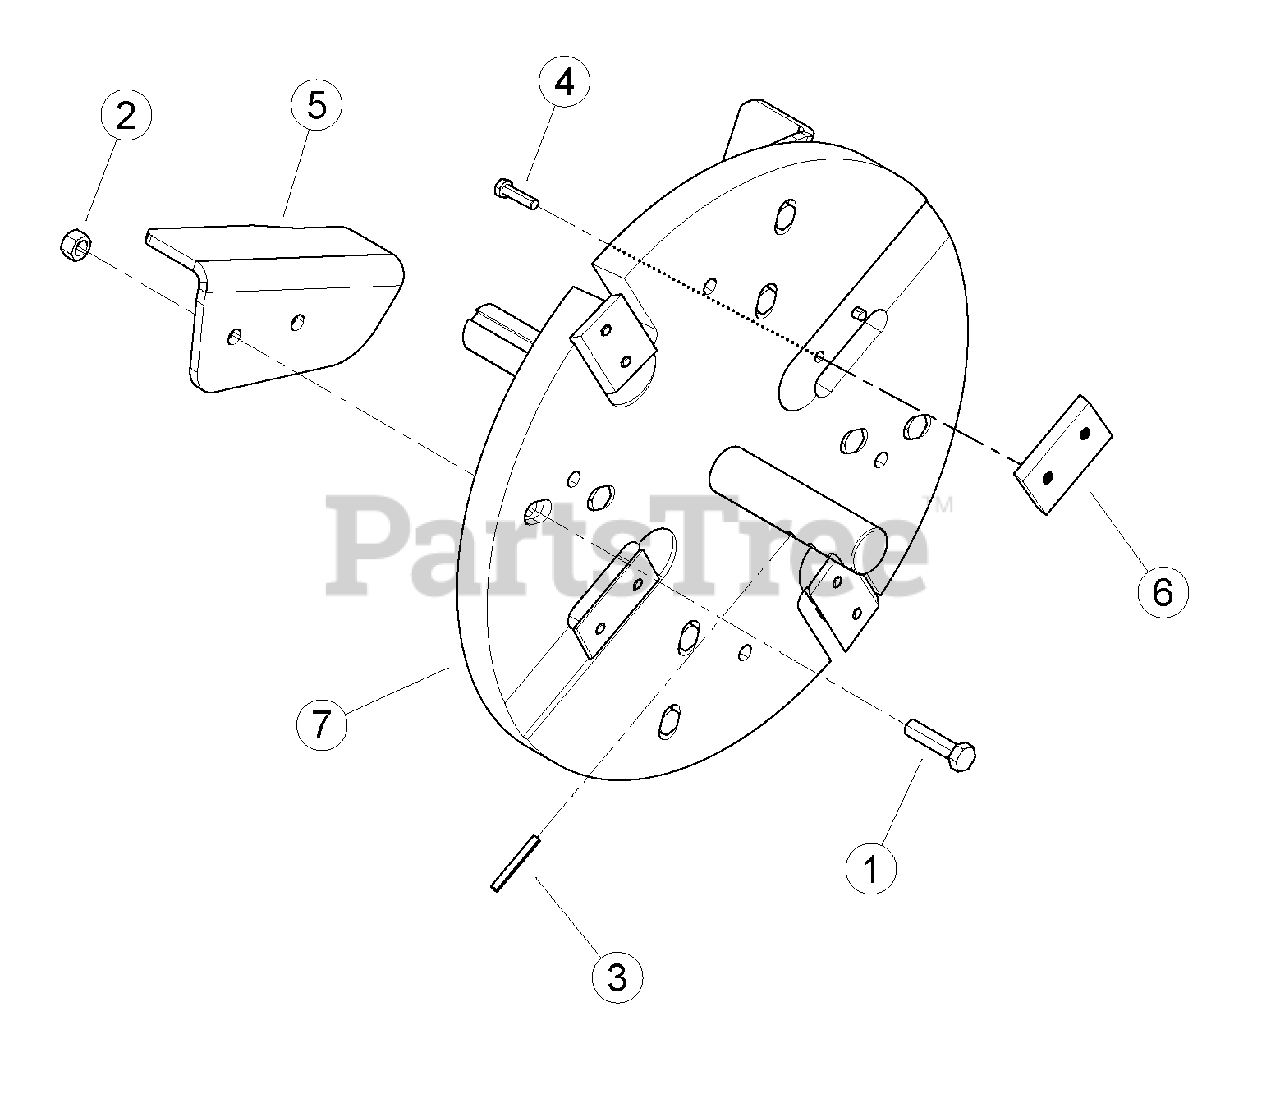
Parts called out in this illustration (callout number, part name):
1	BOLT, 1/2-13 X 2 GR5 HEX CAPSCREW
2	NUT, 1/2-13 GR5 CENTERLOCK GRB
3	SPRINGPIN, 1/4 X 2" LG
4	BOLT, 5/16 X 1-1/4 HEX HD GR8 PATCH
5	PADDLE, 5" CHIPPER
6	KIT, CHIPPER BLADE
7	WELDMENT, CHIPPER ROTOR
